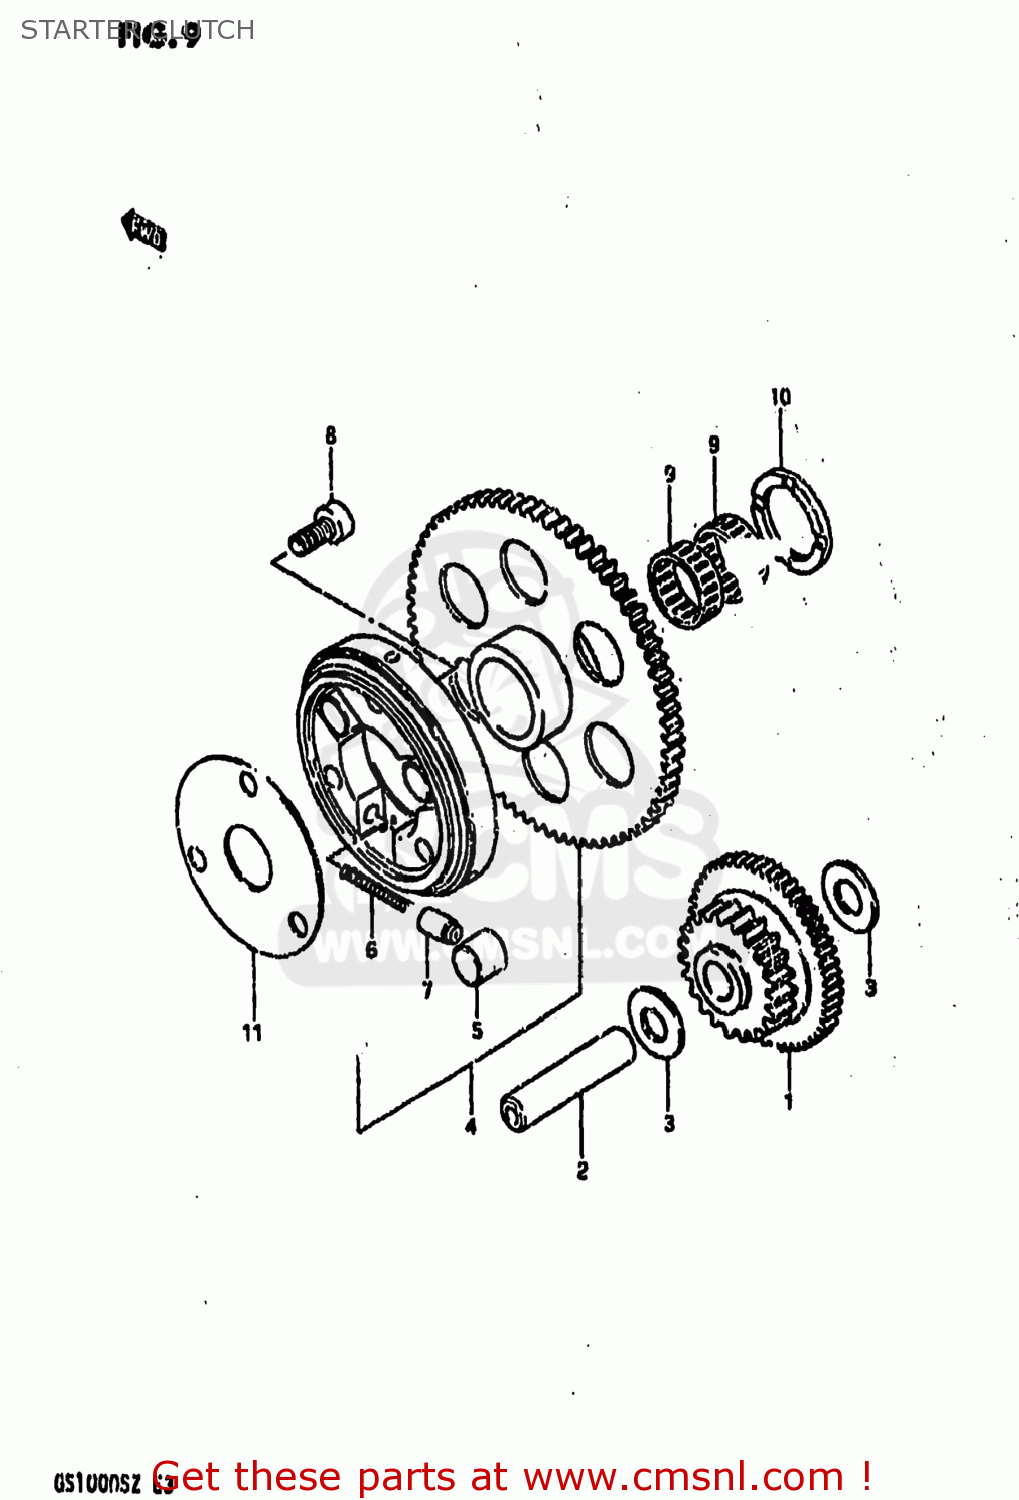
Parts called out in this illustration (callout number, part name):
1	GEAR,STARTER IDLE
2	PIN(7.4X13X56)
3	WASHER(13.3X25X0.85)
4	CLUTCH SET,STARTER
5	ROLLER(15X13)
6	SPRING
7	PIECE,PUSH
8	BOLT
9	BEARING
10	WASHER(25X38X2.5)
11	SHIM,STARTER CLUTCH HUB
